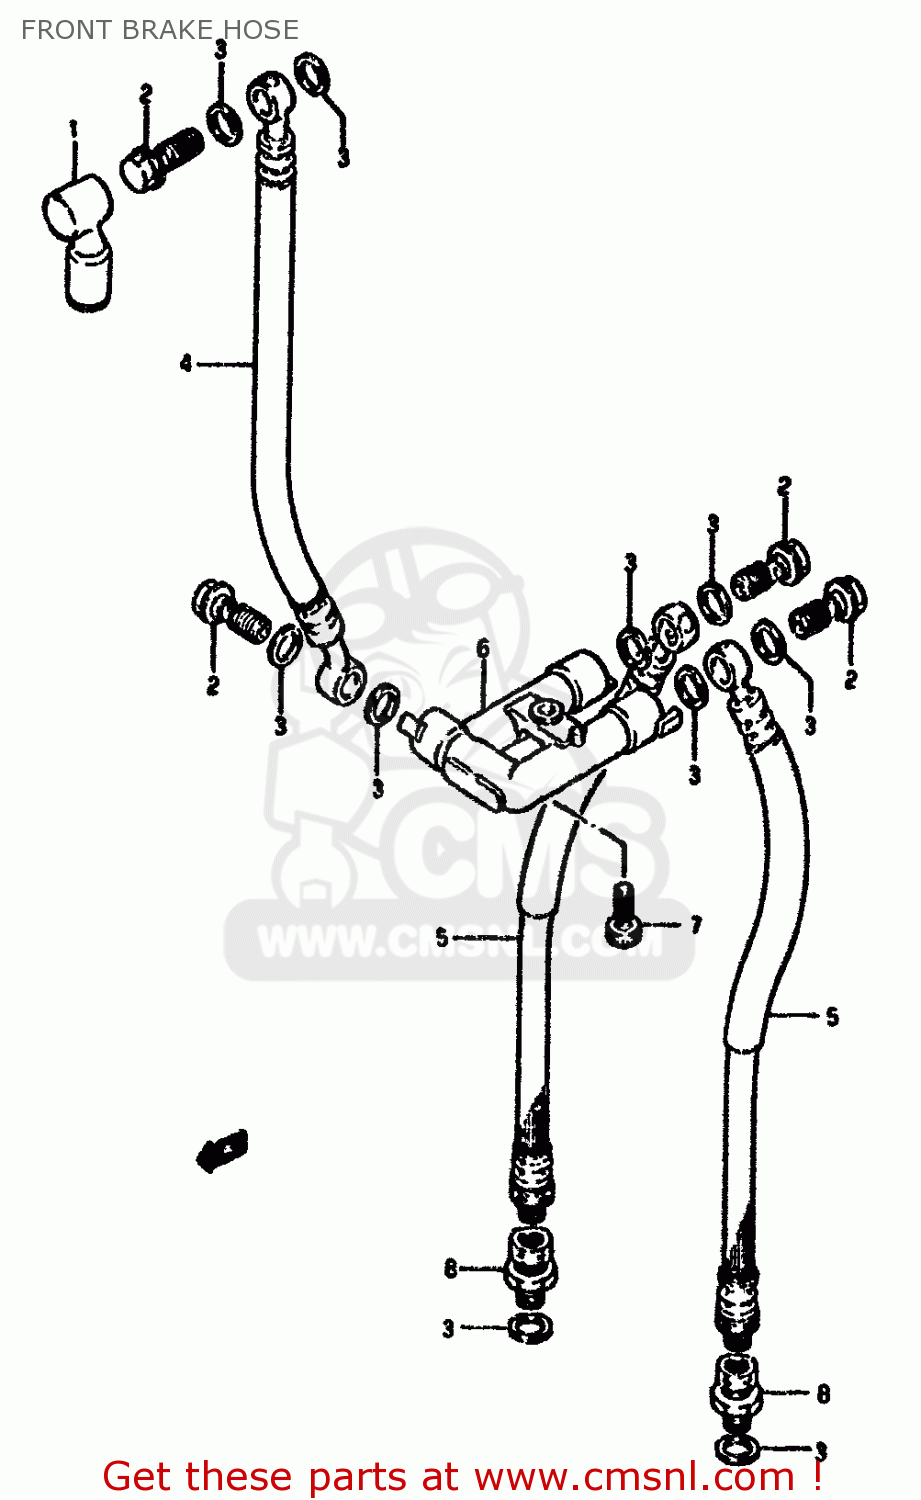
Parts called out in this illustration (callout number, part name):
1	BOOT,MASTER CYLINDER
2	BOLT UNION
3	WASHER(10X15X1.5)
4	HOSE,FRONT BRAKE NO.1
5	HOSE COMP,FRONT BRAKE
6	JOINT,BRAKE HOSE
7	BOLT
8	ADAPTER,BRAKE HOSE
